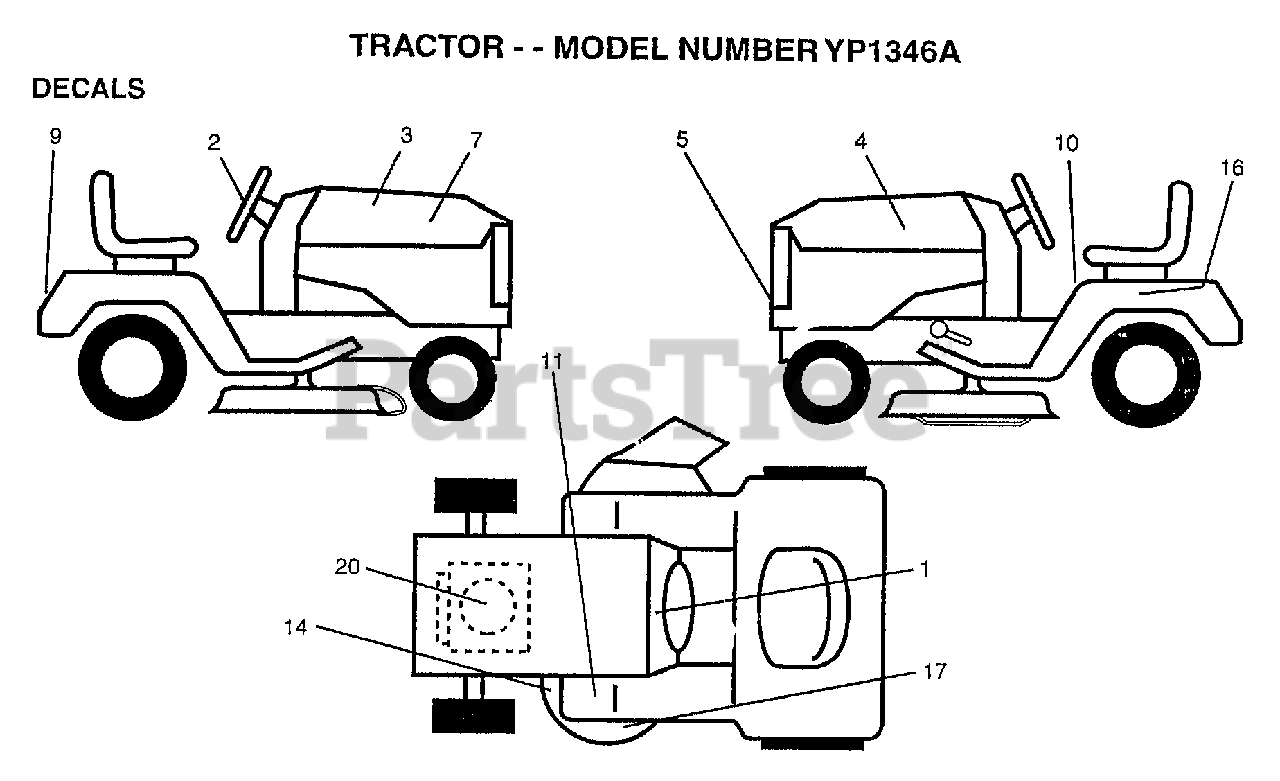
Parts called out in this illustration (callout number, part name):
1	"DECAL DASH,OPER."
2	"DECAL INSERT,STRG"
3	DECAL.HOOD.RH
4	DECAL HOOD LH
9	DECAL FENDER
10	"DECAL DANGER,FEND"
14	DECAL
16	DECAL.BATRY.3-3908
17	DECAL CHASSIS
20	DECAL HP ENGINE
